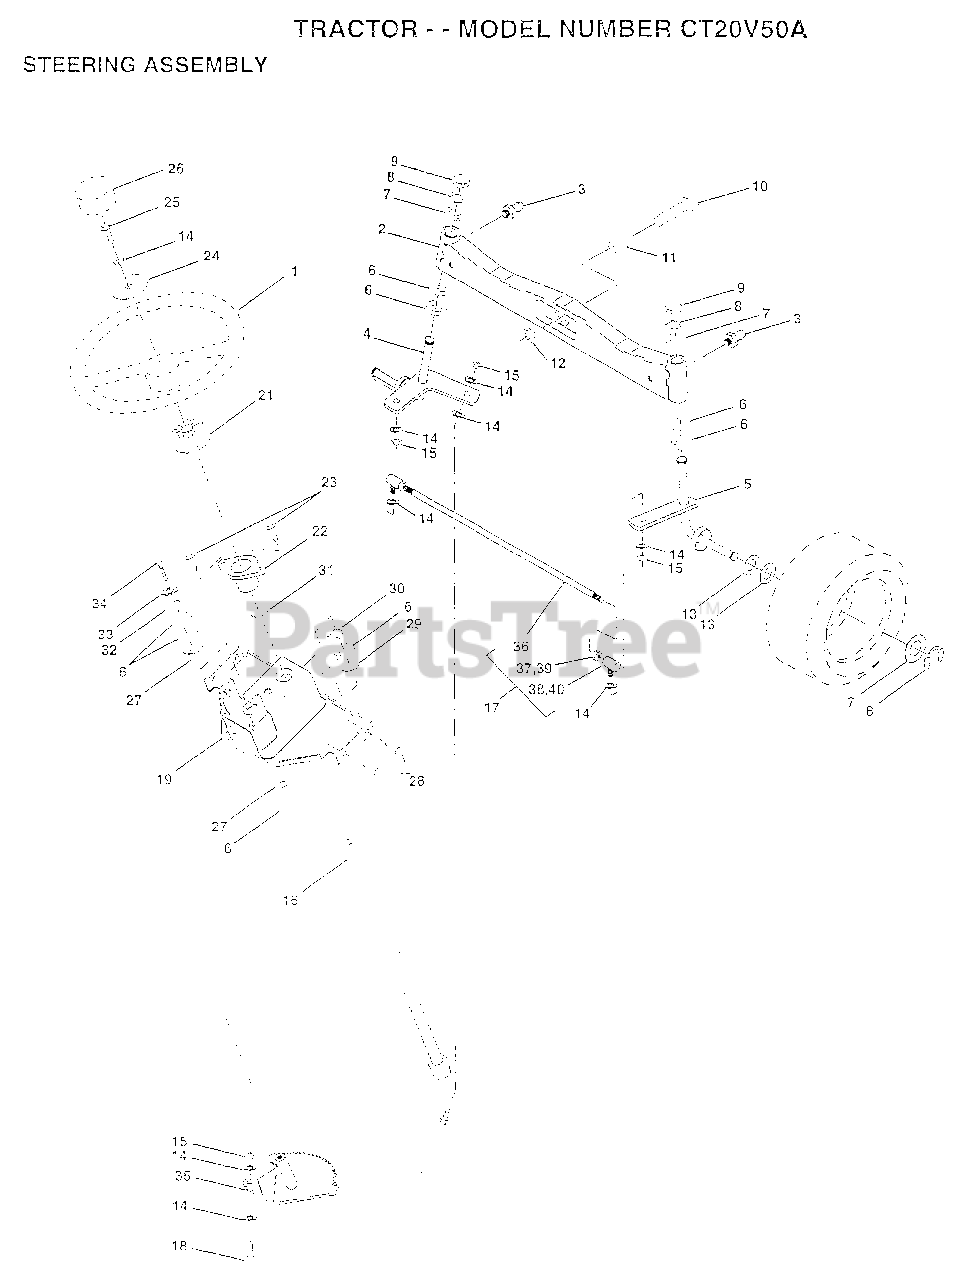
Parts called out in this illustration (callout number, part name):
1	WHEEL STR AYP BLK
3	ZERK M
4	SPINDLE.ASM.LH
6	WASHER .T
7	WASHER
8	RING
9	CAP
10	BOLT
11	SPACER BEARING
12	"NUT-LOC,FLANGE LT"
14	LOCKWASHER
16	SHAFT.STEER.VGT
17	ROD.ASM.TIE.BALL
18	DRAGLINK.BALL.JOI
21	ADAPTER LT
24	WASHER T
25	BOLT
26	CAP STEER AYP
27	COL. SRTG. BEAR.
28	SCREW
29	"FLANGE GT, BEAR."
30	KLIP RING
31	BUSHING.NYLINER.
32	WASHER
33	LOCKWASHER
34	BOLT
35	GEAR.ASM.SECTOR.
37	NUT
38	JOINT.RH
39	NUT
40	JOINT.LH
